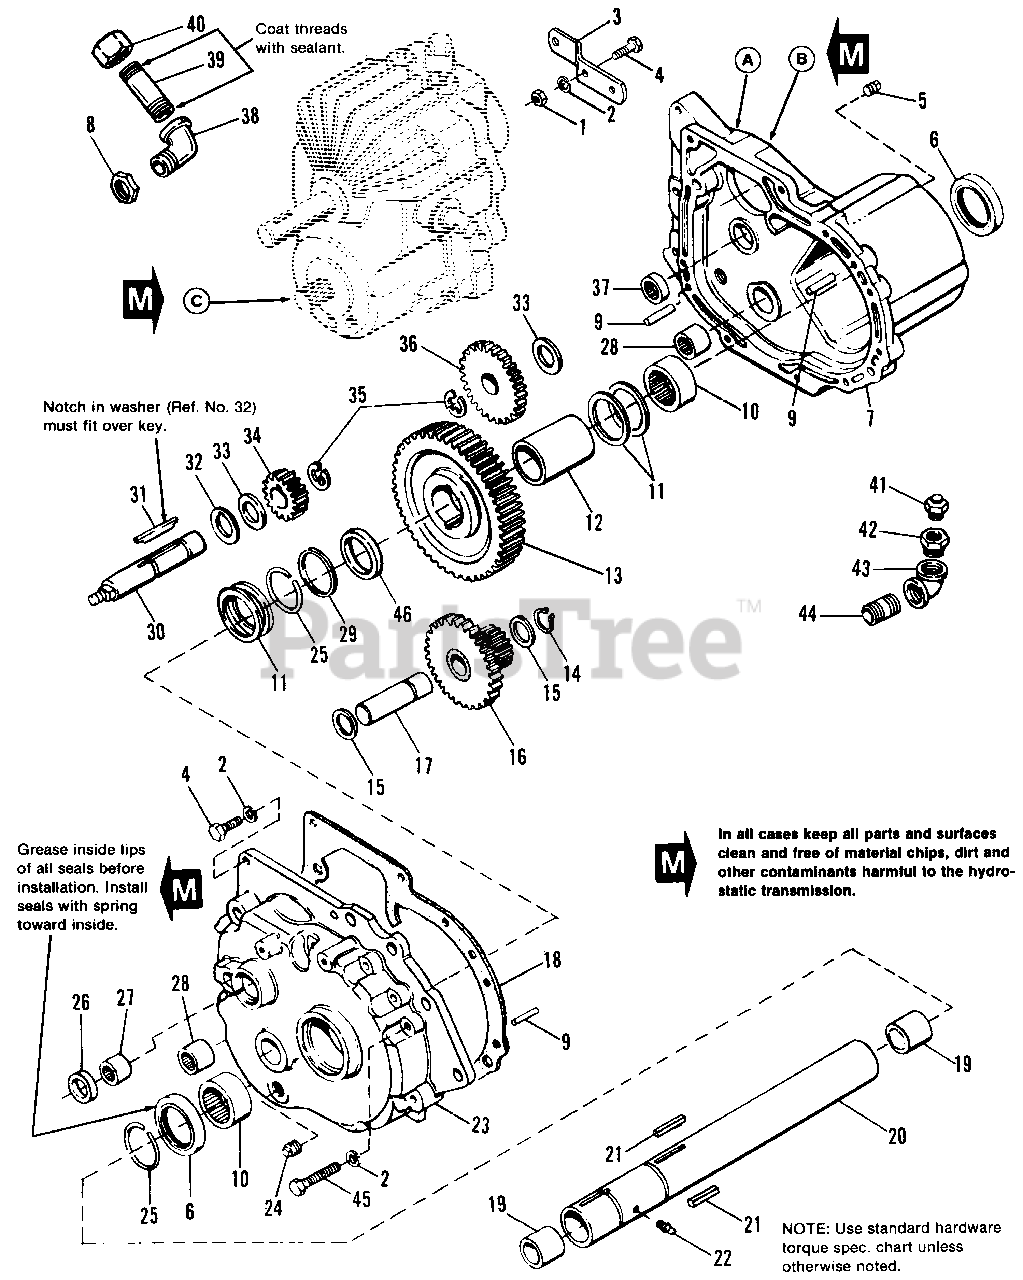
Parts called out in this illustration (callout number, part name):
1	NUT, Hex, Full, 5/16-18
2	LOCKWASHER, 5/16
3	SUPPORT, Spring
4	CAPSCREW, Hex Hd., 5/16-18 x 1
6	SEAL
7	GEAR CASE ASSY., (Incl. Ref. Nos.10, Qty 1; 28, Qty 1 & 37)
8	LOCKNUT, 3/8, Rigid Conduit
9	PIN, Roll, 3/8 x 1
12	SPACER, Axle, L.H.
13	GEAR, Drive
14	RING, Retaining
16	PINION & SHAFT ASSY.
17	SHAFT, Intermediate
18	GASKET
20	TUBE ASSY., Axle (Incl. Ref. No.19)
22	FITTING, Grease
23	COVER ASSY., Grease Case (Incl. Ref. Nos. 10, Qty 1; 27 & 28, Qty 1)
25	RING, Retaining
26	SEAL
28	BEARING, Needle
30	SHAFT, Brake
35	RING, Retaining
37	BEARING, Needle
38	ELBOW, Street
39	NIPPLE, Pipe
41	VALVE, Relief
42	BUSHING, Pipe
43	ELBOW, Pipe
44	NIPPLE, Pipe
45	CAPSCREW, Hex Head 5/16-18 x 2 G5
46	SPACER, Axle, R.H.
